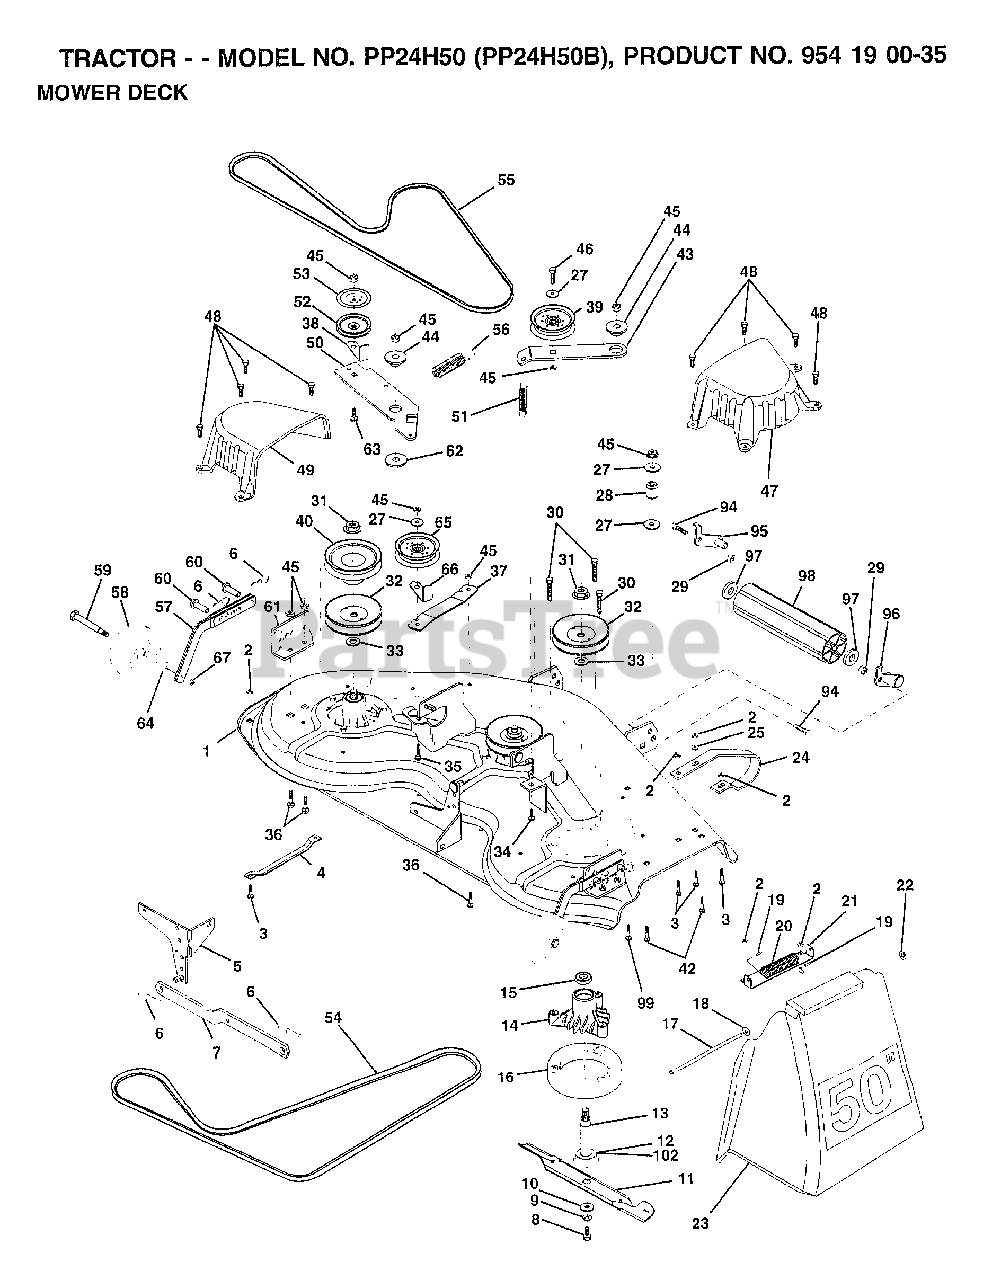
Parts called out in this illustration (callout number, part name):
1	"DECK ASM-50"""
4	RUNNER-LH M
5	BRKT.ASM.SW.44/50
8	BLADE BOLT
10	WASHER.HARD.BLADE
11	"BLADE.50"" HD"
12	BEARING.BALL
13	SHAFT.ASM.W/BRNG
14	HOUSING.MAND.44.V
15	BEARING
16	STRIPPER RND MWR
17	ROD-HINGE T
18	WASHER
19	CAP-SLEEVE LT
20	SPRING TORSION
21	BRKT DEFLECTOR
22	NUT PUSH M
23	DEFLECTOR
24	"RUNNER RH 50"" DK"
25	WASHER M
27	WASHER
29	NUT
30	"SCREW-THD ROLL,WA"
32	PULLEY.MANDREL.42
33	WASHER
34	BOLT.3/8-14X1.25
35	BOLT
36	BOLT D
37	STIFFENER.ARM.IDL
38	"KEEPER-BELT,IDLER"
39	FLAT IDLER PULLEY
40	"PULLEY.DRIVEN.44"""
42	BOLT
43	"ARM.IDLER.SEC.44"""
44	SPACER.RETAINER.MOWER
47	"COVER.MAND.RH.44"""
48	SCREW.1/4-20X5/8
49	COVER.MANDREL.LH
50	ARM.IDLER.PRIMARY
51	"SPRING.SEC.44""VEN"
52	PULLEY.IDLER.VGRO
53	SHIELD.IDLER.44.V
54	BELT V PRIM 50
55	BELT-V.SEC.46.KEL
56	SPRING.EXT.DECK.
57	BAR.ASM.GUAGE.WHL
58	WHEEL GAGE DONUT
59	BOLT.SHOULDER
60	PIN.CLEVIS
61	BRACKET.GUAGE.WHL
62	HARDENED WASHER
63	BOLT.3/8-16X1.50
64	WASHER
65	PULLEY IDELR FLAT
66	"KEEPER-BELT,IDLER"
67	LOCKNUT
94	BOLT
97	WASHER
99	BOLT
102	WASHER.FELT.
